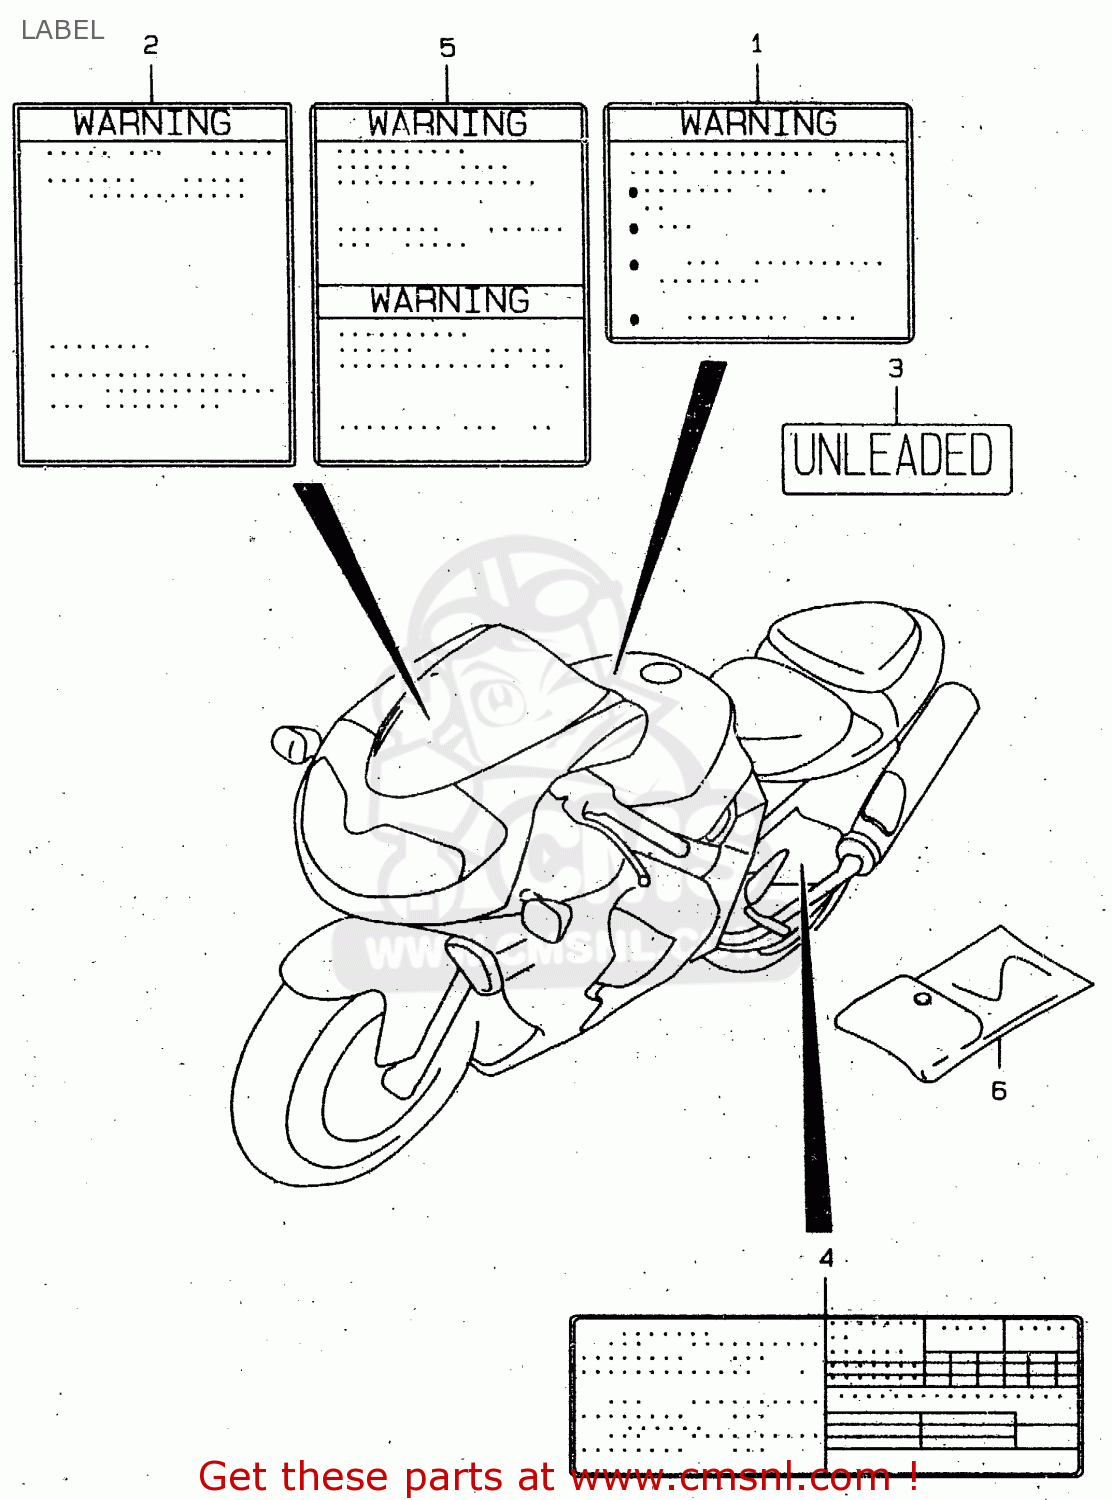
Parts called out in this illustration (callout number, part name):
1	LABEL,WARNING
2	LABEL (WARNING SCREEN)
3	LABEL,CAUTION
4	LABEL, TIRE INFORMATION
5	LABEL,WARNING STEERING
6	BAG COMP,OWNERS MANUAL
